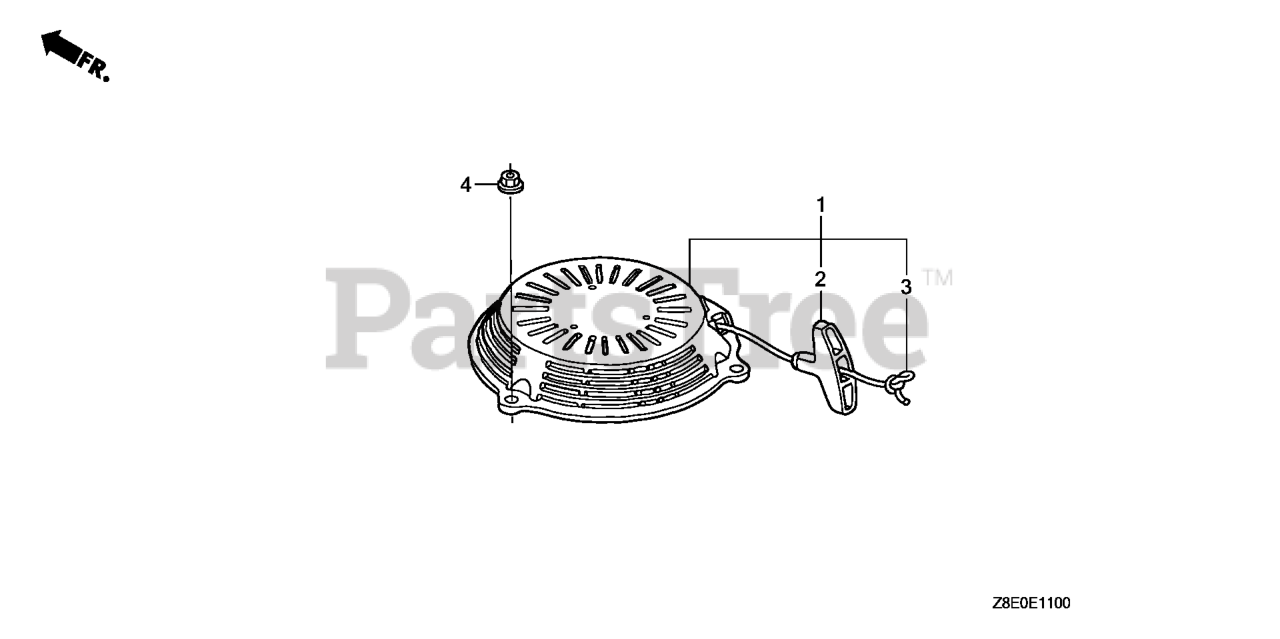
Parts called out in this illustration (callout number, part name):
1	STARTER ASSY. *NH1*
2	KNOB, RECOIL STARTER
3	ROPE, RECOIL STARTER (LONG TYPE)
4	NUT, FLANGE (6MM)
